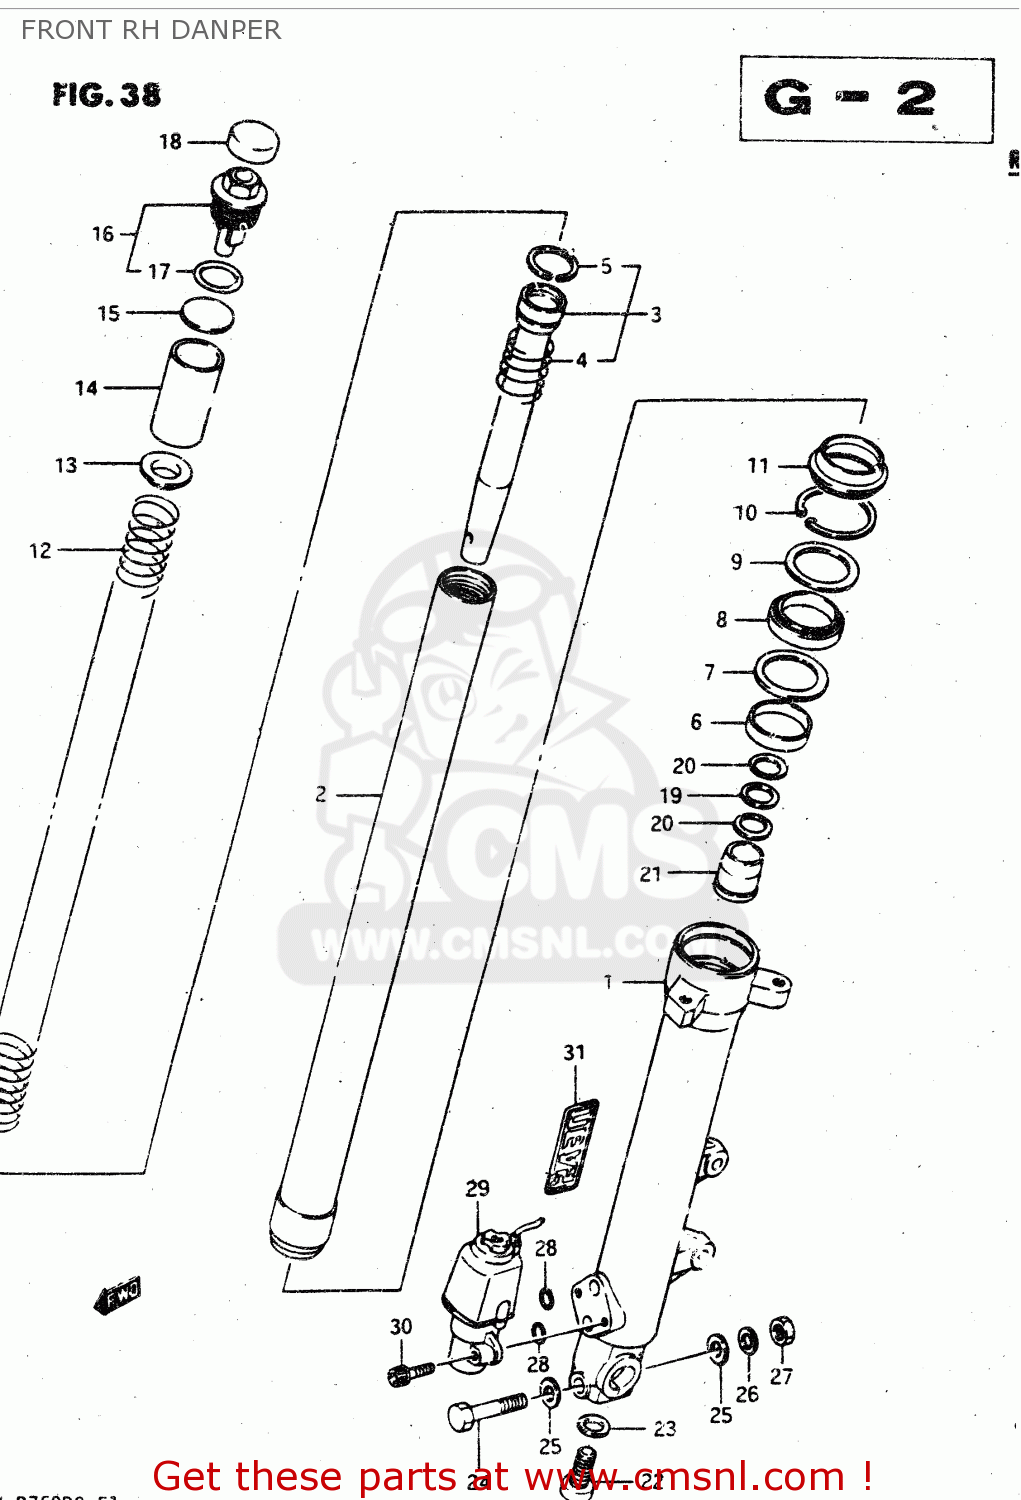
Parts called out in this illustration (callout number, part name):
1	TUBE,OUTER,RIGHT
2	TUBE,FORK INNER
3	CYLINDER
4	SPRING,REBOUND
5	RING,FR FORK PISTON
6	METAL,SLIDE
7	WASHER,FORK OIL SEAL
8	OIL SEAL,FRONT FORK
9	WASHER,FORK OIL SEAL
10	SNAP RING
11	DUST SEAL,FRONT FORK
12	SPRING,FRONT FORK
13	WASHER
14	SPACER
15	WASHER,FR FORK SPRING
16	CAP,FORK INNER TUBE
17	O RING
18	CAP
19	WASHER,OIL LOCK PIECE
20	SPRING,FORK OIL LOCK PIECE
21	PIECE,OIL LOCK
22	BOLT(14X25)
23	GASKET (NAS)
24	BOLT 10X60
25	WASHER
26	LOCK WASHER
27	NUT
28	O RING
29	P.D.F. ASSEMBLY
30	BOLT
